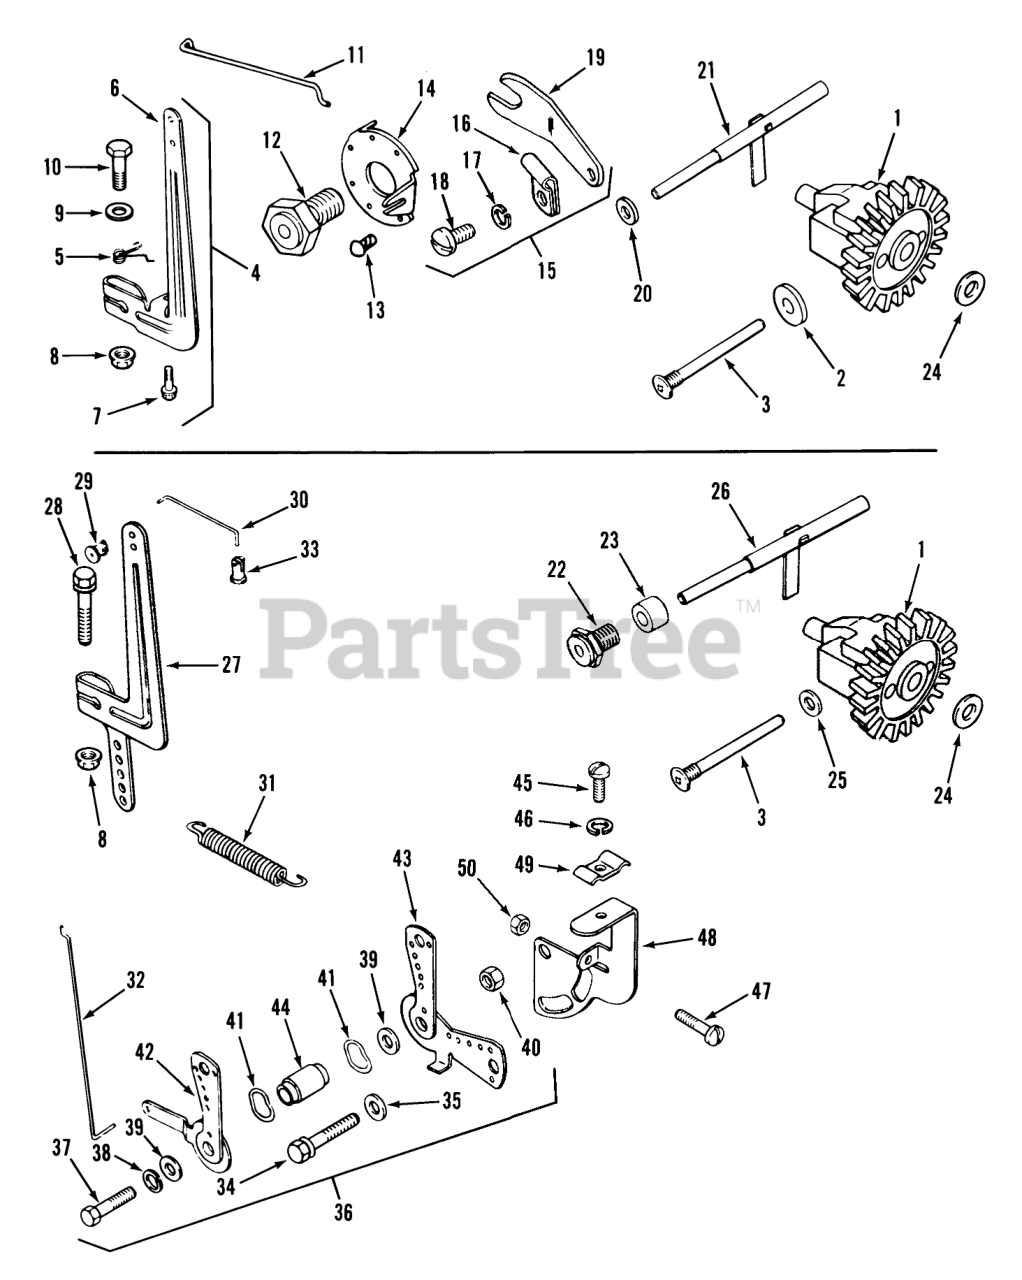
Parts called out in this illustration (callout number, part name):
1	Governor Gear Kit (includes 24)
2	Plain Washer 1/4 308 Only
3	Govenor Stop Pin
4	Governor Lever Assy 308 Only (includes items 5 thru 10)
5	Governor Spring 308 Only
6	Governor Lever 308 Only
7	Hex Wash. Hd. Screw 8-32 x 1/4 308 Only
8	Palnut
9	Washer
10	H.C. Screw 1/4-20 x 1 308 Only
11	Governor Linkage 308 Only
12	Governor Shaft Bushing 308 Only
13	Drive Screw #2 308 Only
14	Regulating Disc 308 Only
15	Speed Control Bracket Assembly 308 Only (includes 16 thru 19)
16	Cable Spring Clip 308 Only
17	Lockwasher #6 308 Only
18	Sltd. Pan Hd. Screw 8-32 x 3/8 308 Only
19	Speed Control Bracket 308 Only
20	Plain Washer 1/4
21	Governor Cross Shaft 308 Only
22	Bushing
23	Spacer
24	Washer
25	Washer
26	Governor Cross Shaft Kit
27	Governor Lever
28	Screw
29	White Bushing 310, 312, 414, 416
30	Linkage (Governor to Carb.)
31	Spring (Governor to Cab.)
32	Choke Linkage (Carb. to Choke Shaft)
33	Yellow Bushing 310, 312, 414, 416
34	Screw
35	Washer
36	Choke Lever Assy (includes items 37 thru 44) 310, 312, 414, 416
37	Screw
38	Washer-Lock
39	Washer
41	Washer
42	Choke Control Lever
43	Lever-Throttle Control
44	Space
45	F.H.M. Screw #10-24 x 1/2
46	Lockwasher #10
47	Screw
48	Bracket-Clutch Control
49	Clamp
